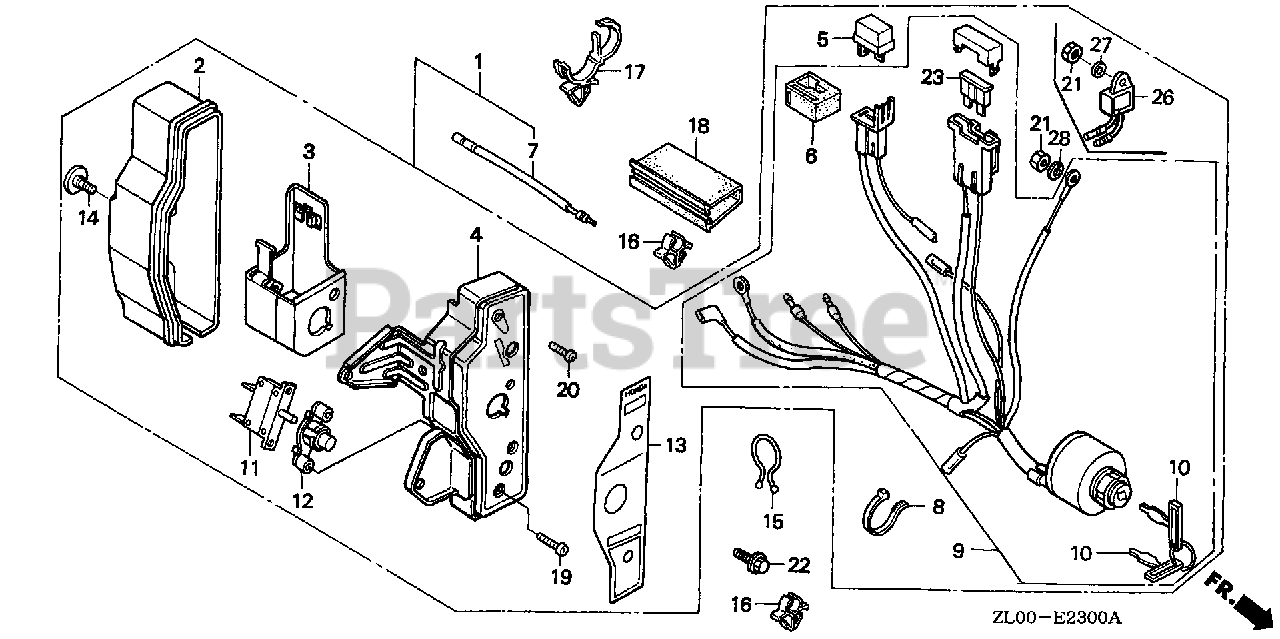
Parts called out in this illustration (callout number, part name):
1	BOX ASSY., CONTROL *NH1* (EXP-ALERT) (BLACK)
1	BOX ASSY., CONTROL *R280* (EXP-ALERT) (POWER RED)
2	CASE, CONTROL
3	BRACKET, CASE MOUNTING
4	PANEL, CONTROL *NH1* (BLACK)
4	PANEL, CONTROL *R280* (POWER RED)
5	RECTIFIER ASSY., SILICON (SHINDENGEN)
6	SUSPENSION, CONNECTOR
7	SUB-WIRE HARNESS
9	SWITCH ASSY., COMBINATION
11	PROTECTOR, CIRCUIT (1.0A)
12	LENS ASSY., PROTECTOR
13	MARK, CONTROL BOX (EXP)
14	SCREW, SPECIAL (6X12)
15	CLIP, PURSE LOCK
16	CLIP, CORD
17	STRAP, WIRE HARNESS (25MM) (BLACK)
18	TUBE, FASTENER (30MM)
19	SCREW, PAN (3X12)
20	SCREW, PAN (4X12)
21	NUT, HEX. (4MM)
22	BOLT, FLANGE (6X10)
23	FUSE, BLADE (5A)
26	ALERT UNIT, OIL
27	WASHER, PLAIN (4MM)
28	WASHER, SPRING (4MM)
